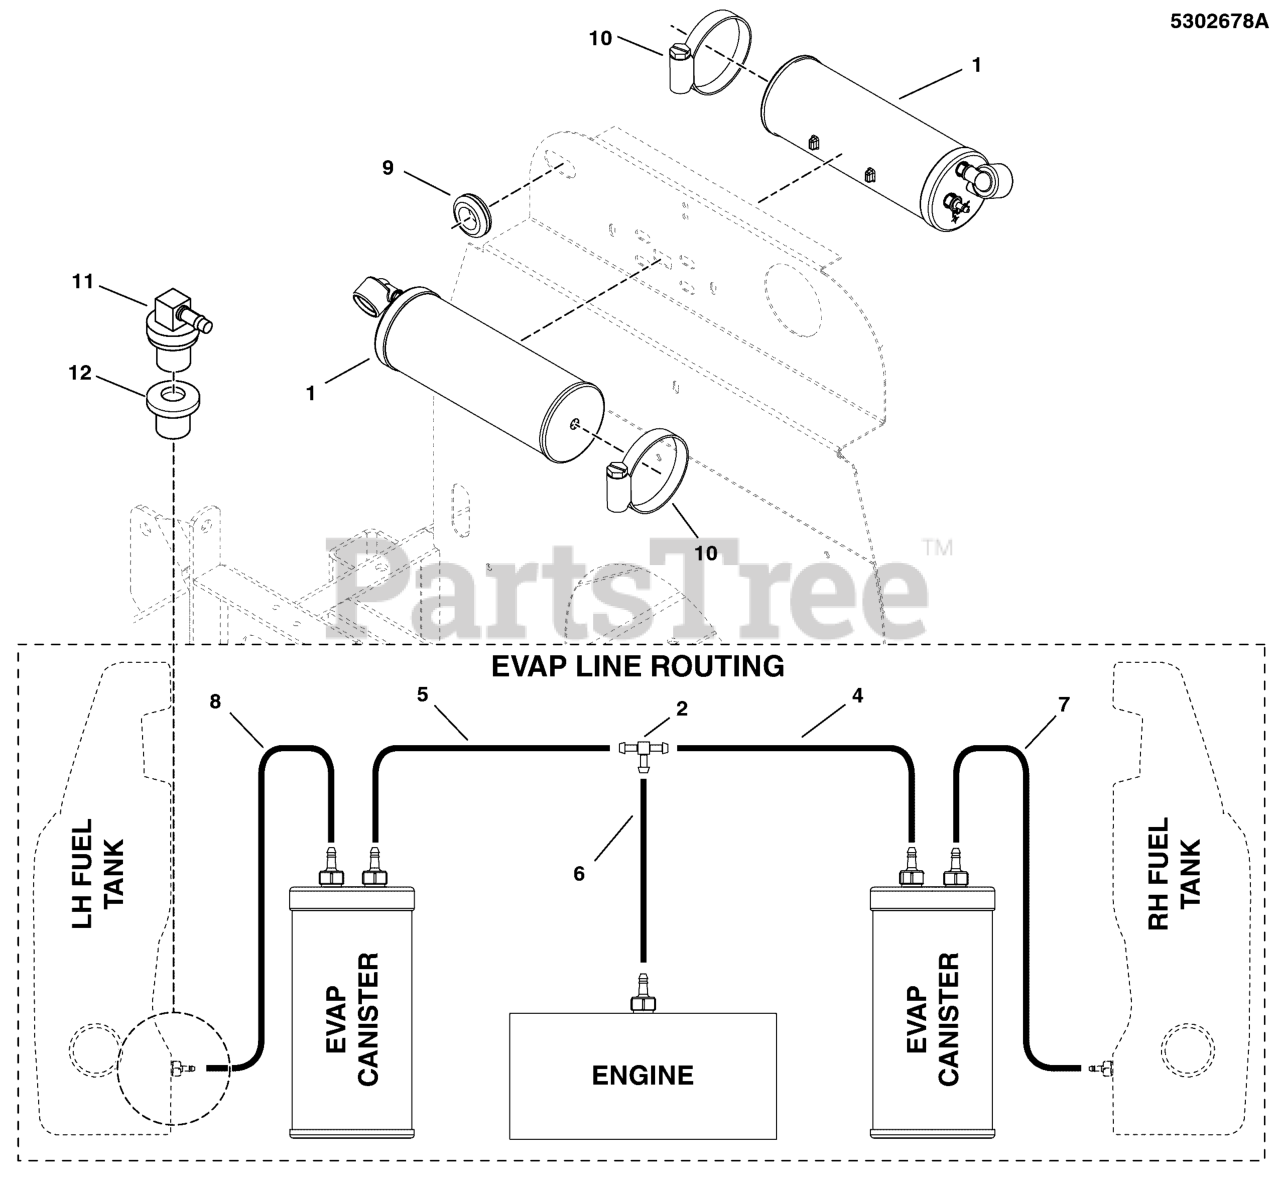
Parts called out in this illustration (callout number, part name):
1	CNSTR, CARB, 9 GAL
2	FITTING, 3/16" TEE, BARB TYPE, HDPE
4	HOSE, VAPOR, 5MM ID, 15.00 LG
5	HOSE, VAPOR, 5MM ID, 1.50 LG
6	HOSE, VAPOR, 5MM ID, 18.50 LG
7	HOSE, VAPOR, 5MM ID, 42.50 LG
8	HOSE, VAPOR, 5MM ID, 39.00 LG
9	GROMMET, 7/8"
10	CLAMP-HOSE WORM DR
11	REMOTE VENT ASSEMBLY
12	GROMMET (SV)
